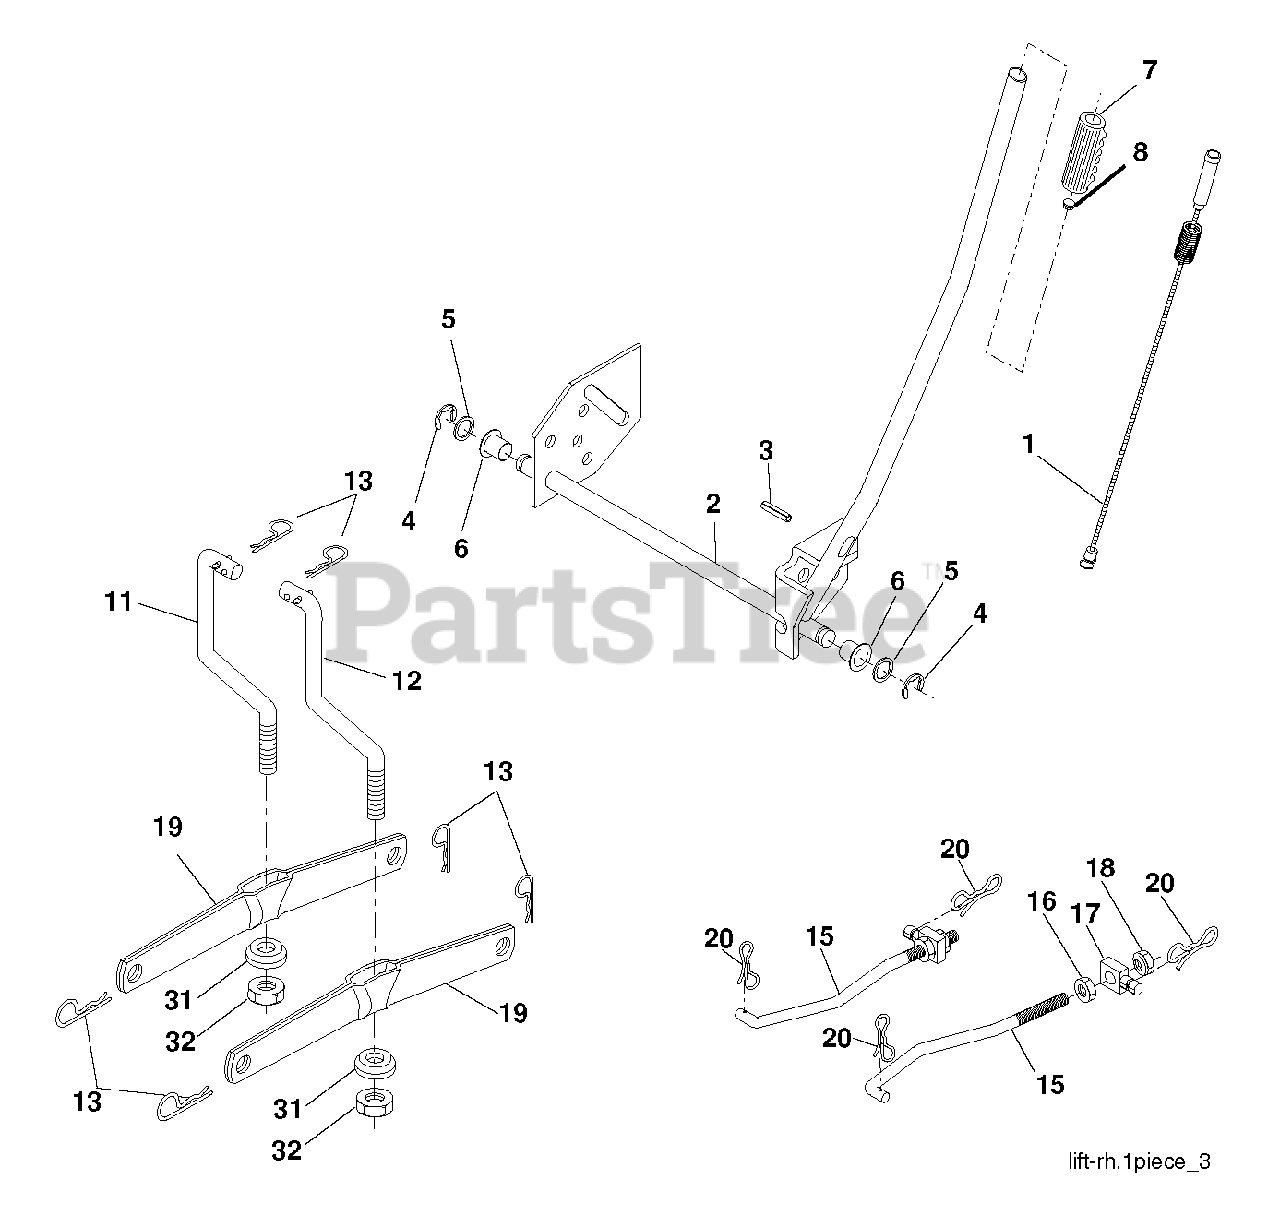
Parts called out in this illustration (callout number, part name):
1	PLUNGER.ASM.LIFT.LVR.BLK.17.32
2	SHAFT ASM R HANDLE
4	RETAINING RING LT
6	BEARING.NYLON
7	GRIP
8	PLUNGER BUT KIT
11	LINK
12	LINK
13	RETAINER-SPRNG RB
15	LINK.SUSPENSION.FRONT
16	NUT
18	NUT
19	ARM.REAR.SUSPENSION
20	PIN.COTTER.7/16.BOW TI
31	BEARING.PIVOT.LIFT
32	NUT CROWNLOCK 3/8-24
